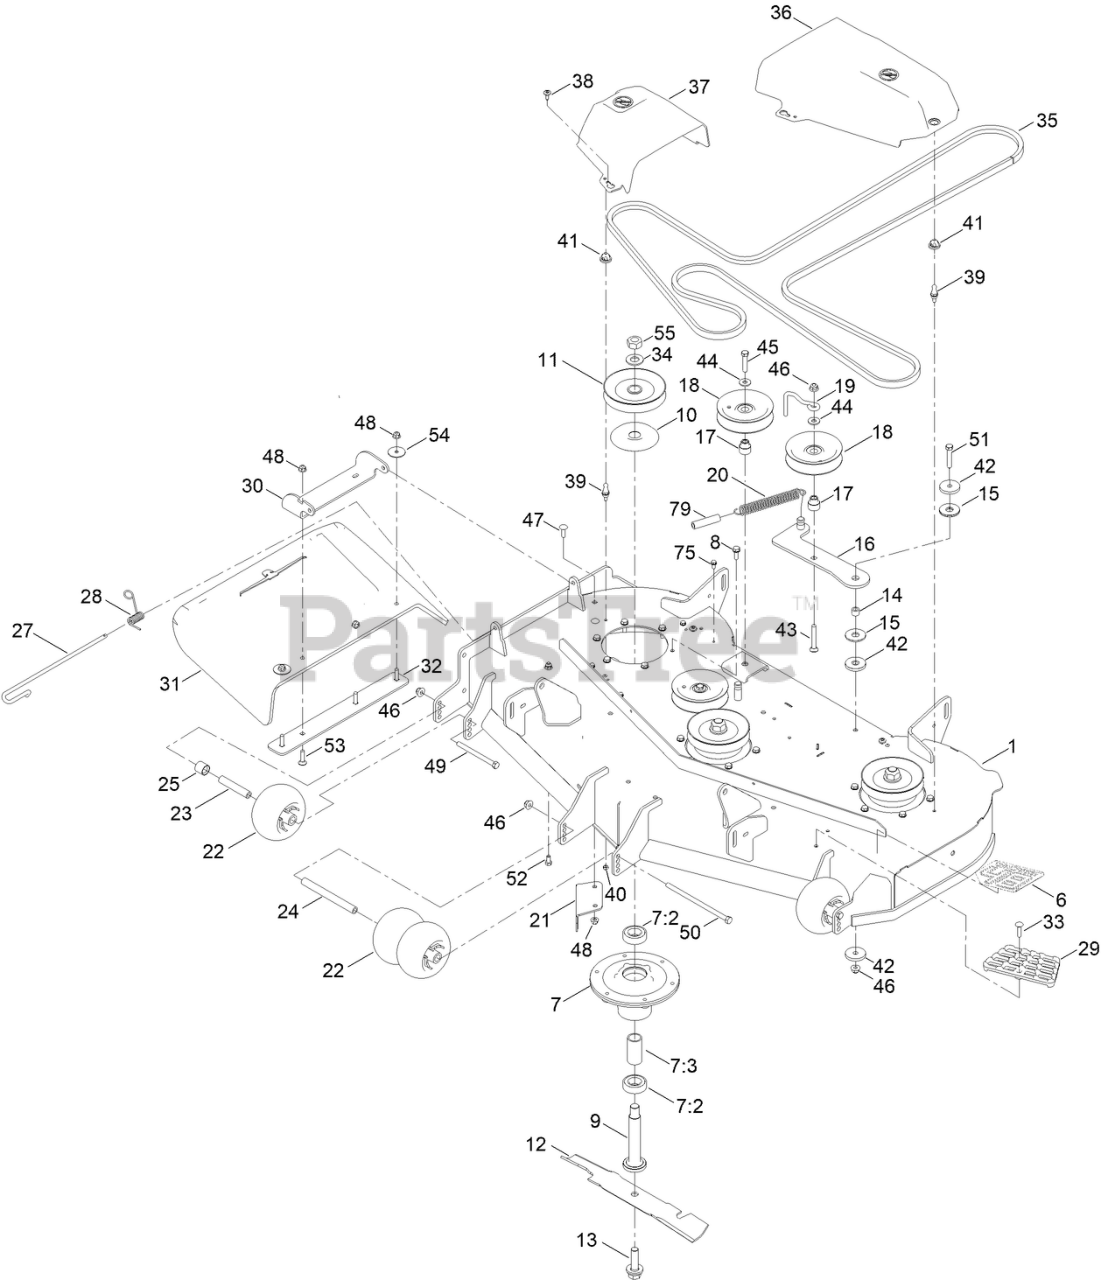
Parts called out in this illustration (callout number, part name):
1	48 IN DECK DECAL ASM
6	DECAL - DECK 48
7	SPINDLE ASM
7:2	BEARING-BALL
7:3	SPACER-BEARING
8	SCREW-TAPTITE
9	SHAFT-SPINDLE
10	SHIELD-BEARING
11	PULLEY
12	BLADE-HI FLO, 16.50 INCH
13	SCREW-BLADE
14	SPACER
15	WASHER-FRICTION, COMPOSITE
16	IDLER ARM ASM
17	BUSHING-IDLER
18	PULLEY-IDLER, FLAT
19	GUIDE-BELT, IDLER
20	SPRING-EXTENSION
21	BAFFLE-CUTOFF
22	ROLLER-SCALP, ANTI
23	TUBE-SPANNER
24	SPACER-WHEEL
25	SPACER-AXLE, REAR
27	PIN-CHUTE
28	SPRING-TORSION
29	STEP-DECK
30	BRACKET-DEFLECTOR, UPPER
31	DEFLECTOR - MOLDED
32	PLATE-DEFLECTOR
33	BOLT-CARRIAGE
34	WASHER
35	V-BELT
36	COVER-BELT, LH
37	COVER-BELT, RH
38	SCREW-SHOULDER
39	STUD-BALL
40	NUT-LOCK
41	GROMMET-BALL
42	WASHER-PLAIN
43	SCREW-CARR
44	WASHER-HARDENED
45	SCREW-HH
46	NUT-HF, NI
47	SCREW-CARR
48	NUT-HF, NI
49	SCREW-HH
50	SCREW-HH
51	SCREW-HH
52	SCREW-HH
53	SCREW-CARR
54	WASHER-FLAT
55	NUT-HEX
75	SCREW-HWH
79	HOSE-BREATHER
